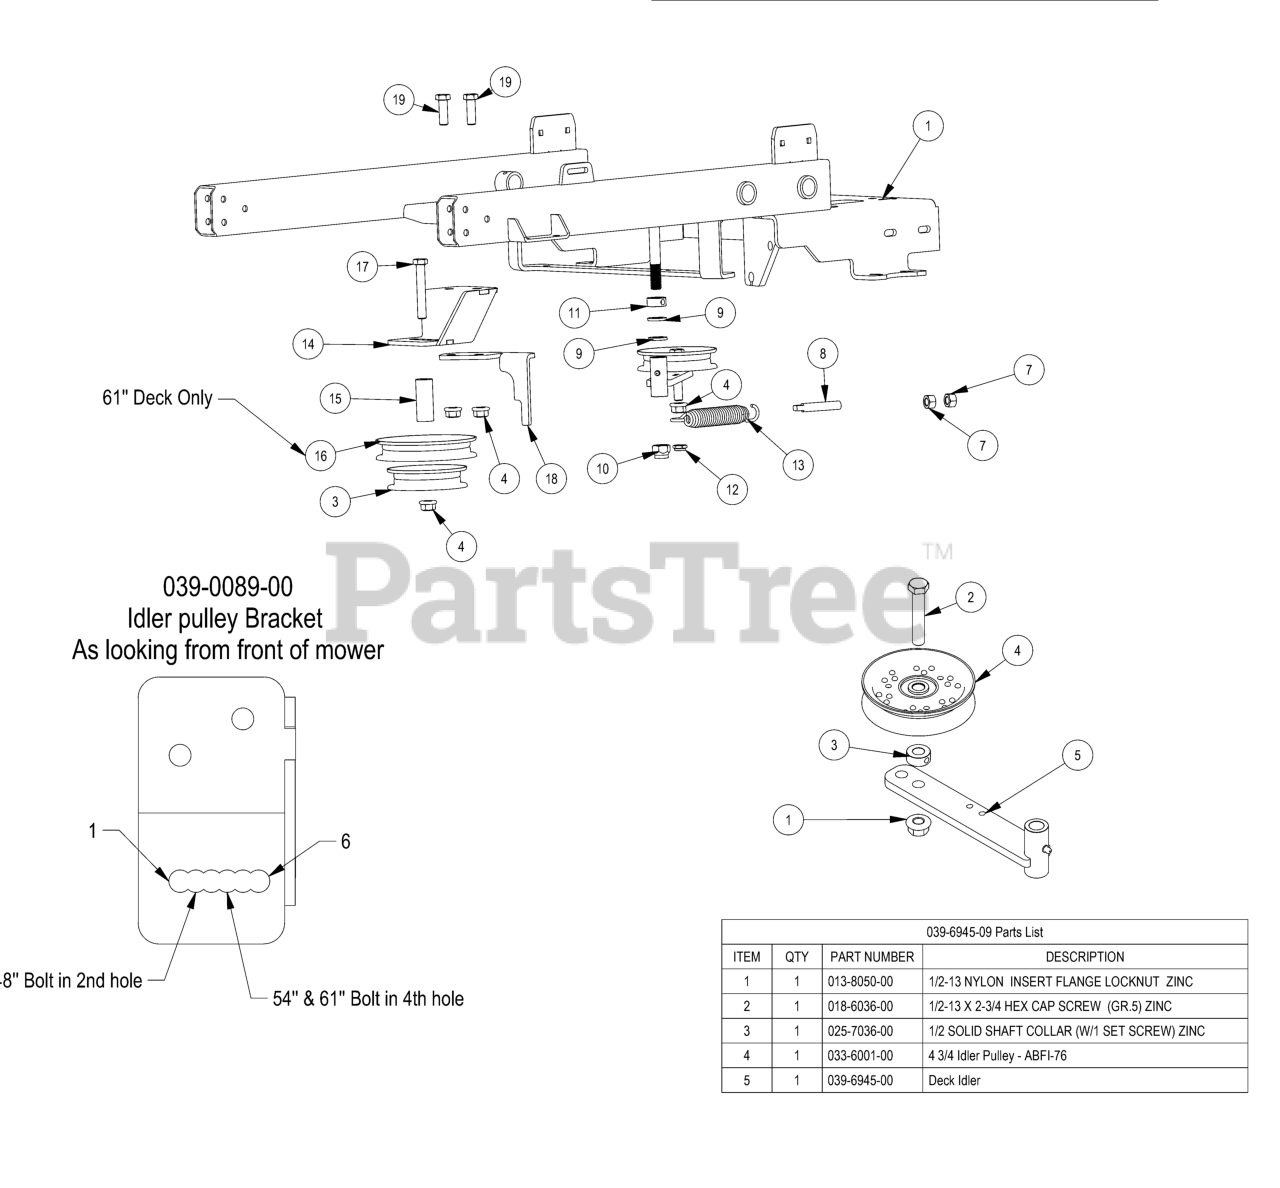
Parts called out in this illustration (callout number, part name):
1	2019 Stand On Frame
2	Deck Idler
3	4 3/4 Idler Pulley
4	1/2-13 NYLON INSERT FLANGE LOCKNUT ZINC
5	1/2-13 X 2-3/4 HEX CAP SCREW (GR.5) ZINC
6	1/2 SOLID SHAFT COLLAR (W/1 SET SCREW) ZINC
7	1/2-13 HEX NUT ZINC
8	All Thread
9	.635 ID X 1.120 OD X .140 THICK FLAT WASHER NYLON
10	5/8-11 NYLON INSERT LOCKNUT ZINC
11	5/8 SOLID SHAFT COLLAR (W/1 SET SCREW) ZINC
12	1/2-13 NYLON INSERT JAM LOCKNUT ZINC
13	Deck Idler Spring
14	Idler Pulley Bracket Weldment 2019 Stand On
15	Stand On Spacer 2.5''
16	5-3/4 Idler Pulley-Capitol Stampings
17	1/2-13 X 3-1/4 HEX CAP SCREW (GR.5) ZINC
18	2019 Stand On Clutch Stop Bracket
19	1/2-13 X 1-1/2 HEX CAP SCREW (GR.5) ZINC
